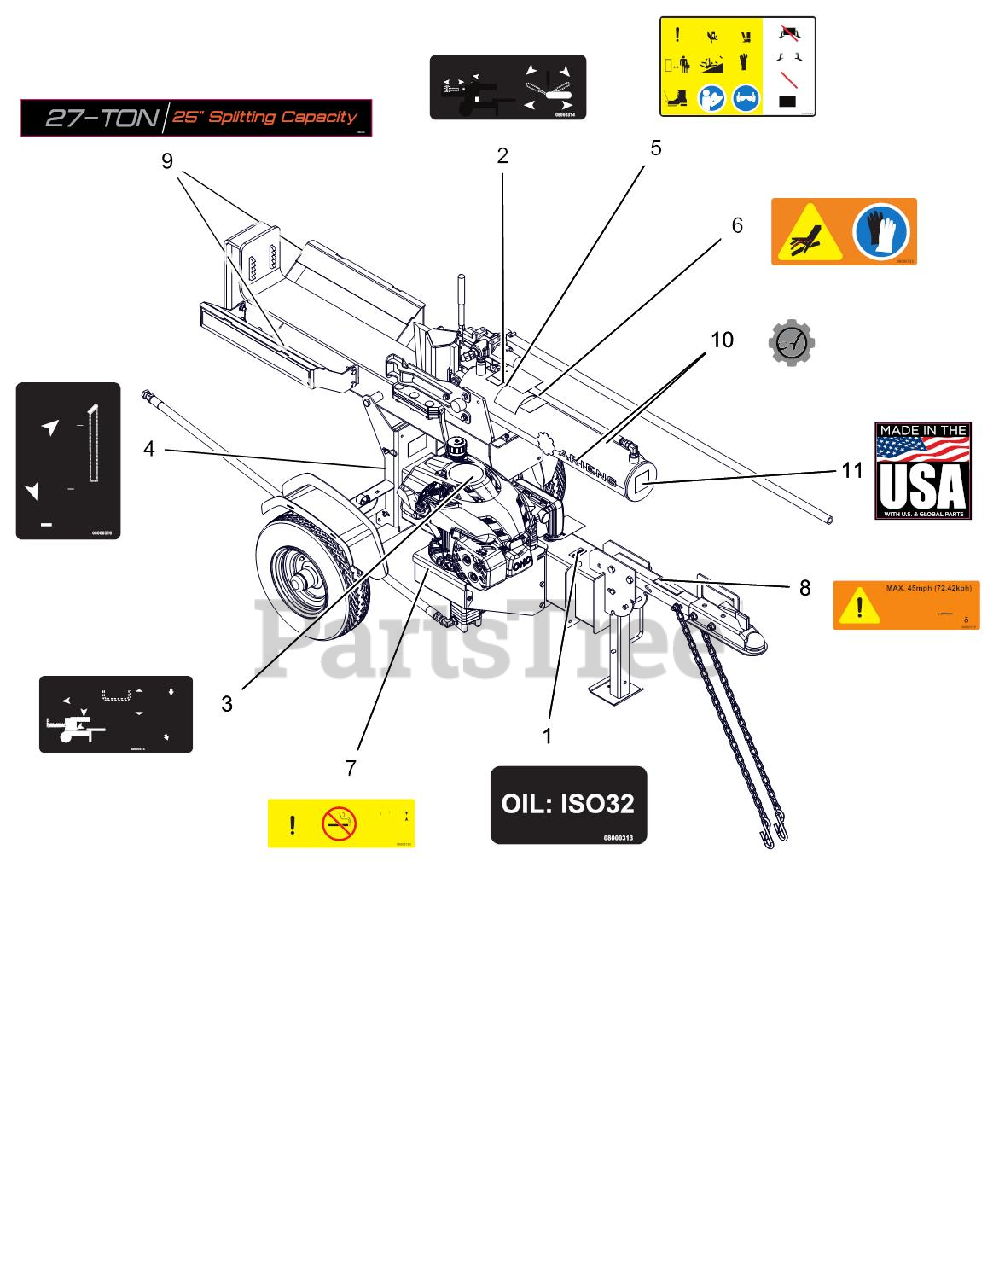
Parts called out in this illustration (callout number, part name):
1	DECAL, LOG SPLITTER-HYD OIL
2	DECAL, LOG SPLITTER-RAM OP
3	DECAL, LOG SPLITTER-TILT OP
4	DECAL, LOG SPLITTER-REAR STAND
5	DECAL,DANGER LOG SPLITTER
6	DECAL,HYD WARNING
7	DECAL,FUEL WARNING
8	DECAL,TOWING
9	DECAL-CRADLE-27 TON
10	DECAL-ARIENS-CYLINDER
11	DECAL, MADE IN USA
